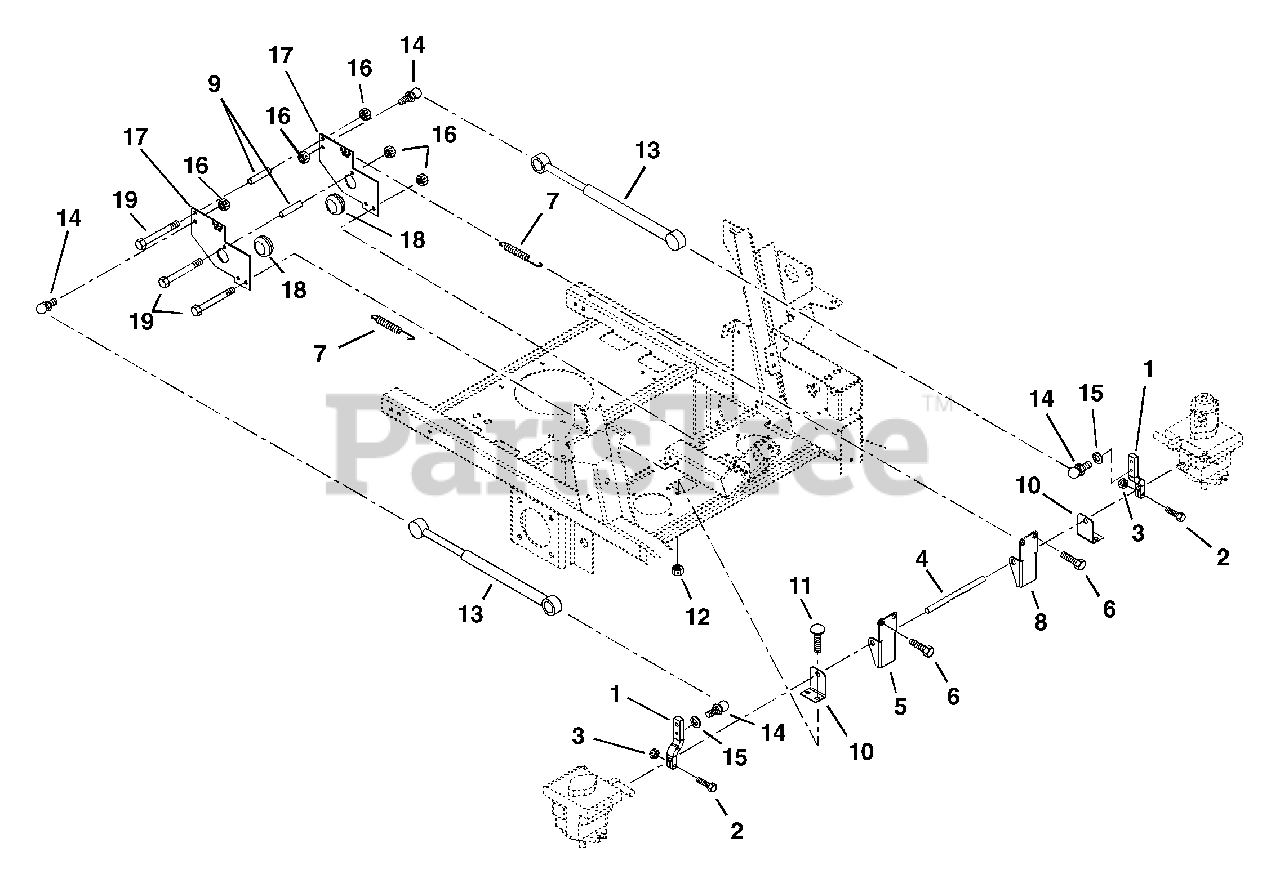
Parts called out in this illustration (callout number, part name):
1	Arm-Pump Actuating
2	Bolt-Hex .25 - 20 x 1.25 Grade 5
3	Nut-Locking-Center .25 - 20
4	Rod-Pivot
5	Pivot-Neutral Right-Hand
6	Bolt-Hex .31 - 18 x 1.00 Grade 5
7	Spring-Tension .085 x .60 x 5.13
8	Pivot-Neutral Left-Hand
10	Support-Pivot Rod
11	Bolt-Round Head Square Neck .31 - 18 x .75
12	Nut-Locking-Nylon .312 - 18
13	Dampener Control
14	Stud-Ball
15	Washer-Locking .31 x .078
16	Nut-Locking-Center .31 - 18
17	Anchor-Damper
18	Grommet .125 x 1.000
19	Bolt-Hex .31 - 18 x 2.75 Grade 5
